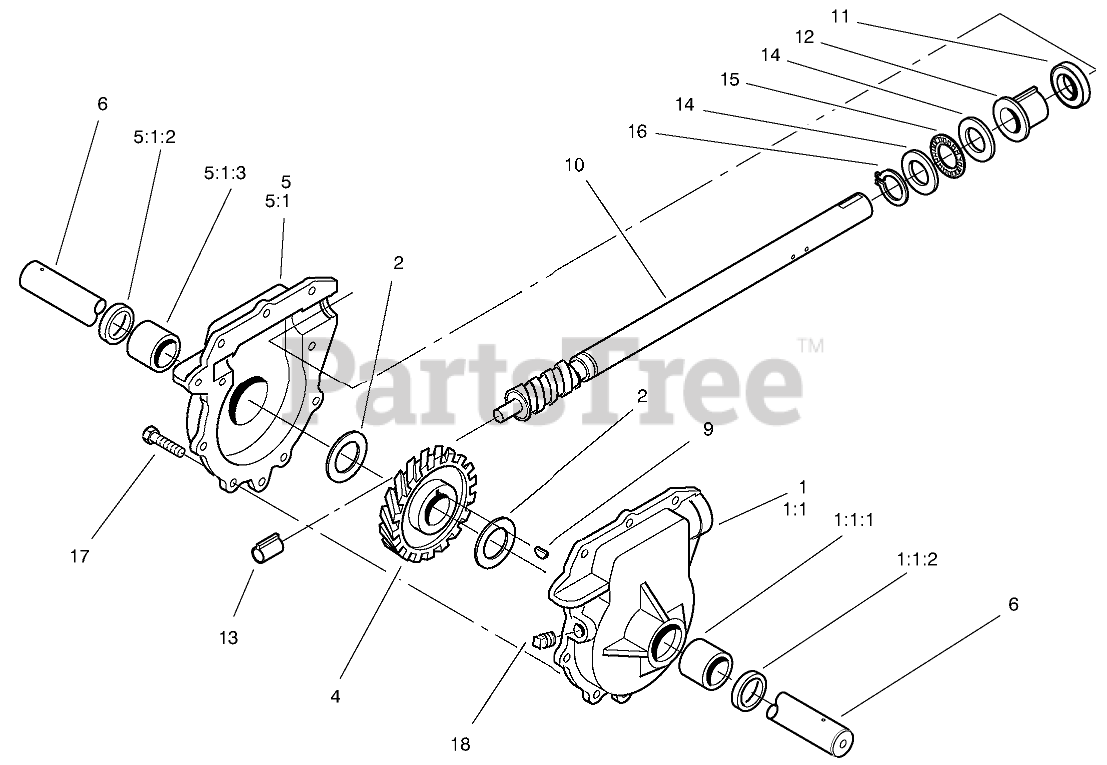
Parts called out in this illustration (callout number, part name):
1	LH AUGER GEARCASE ASM
1:1	Gearcase-Auger, LH
1:1:1	BUSHING
1:1:2	SEAL-OIL
2	WASHER-THRUST
4	GEAR-HELICAL
5	RH AUGER GEARCASE ASM
5:1	GEARCASE-AUGER, RH
5:1:2	SEAL-OIL
5:1:3	BUSHING
6	SHAFT-AUGER
9	KEY-WOODRUFF
10	SHAFT-IMPELLER
11	SEAL-OIL
12	BUSHING-INPUT
13	BUSHING-WORM
14	WASHER-THRUST
15	BEARING-THRUST
16	RING-RETAINING, Ext
17	SCREW-HWH
18	PLUG-PIPE, SQH
